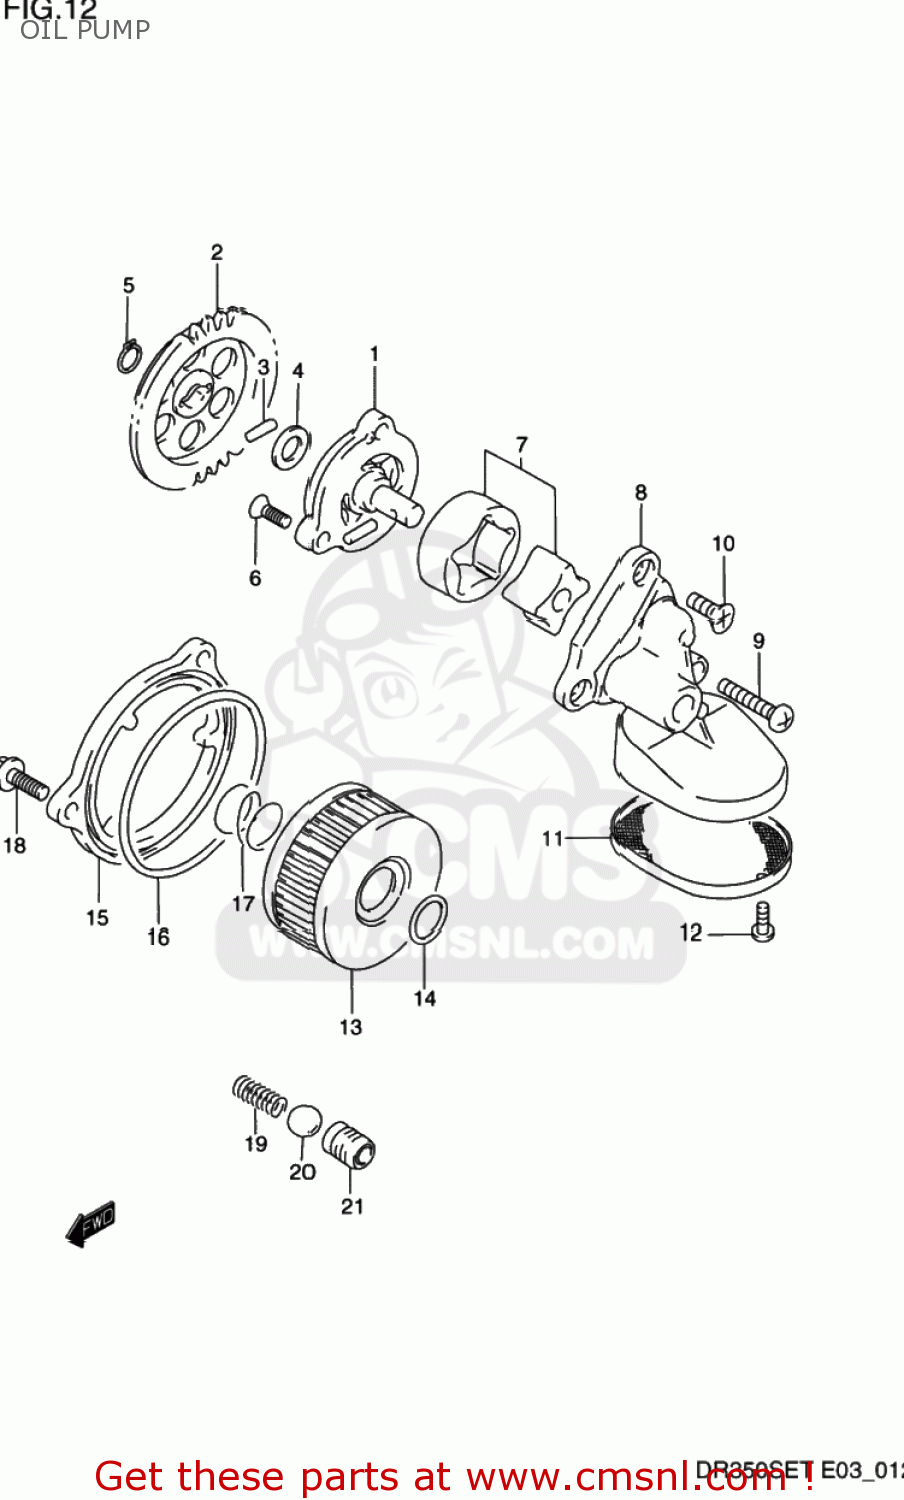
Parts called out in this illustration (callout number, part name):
1	PUMP ASSY,ENGINE OIL NO.1
2	GEAR,OIL PUMP DRIVEN
3	PIN(4X15.8)
4	SHIM
5	CIRCLIP,10MM
6	SCREW ,6X16
7	ROTOR SET,OIL PUMP,NO.2
8	COVER,OIL PUMP NO.2
9	SCREW,6X30
10	SCREW ,6X16
11	STRAINER,OIL PUMP NO.2
12	SCREW
13	FILTER ASSY,ENGINE OIL
14	O RING(D:2.4,ID:15.8)
15	CAP,OIL FILTER
16	O RING(D:2.4,ID:73)
17	SPRING
18	BOLT
19	SPRING
20	BALL
21	SEAT,OIL CHECK VALVE
